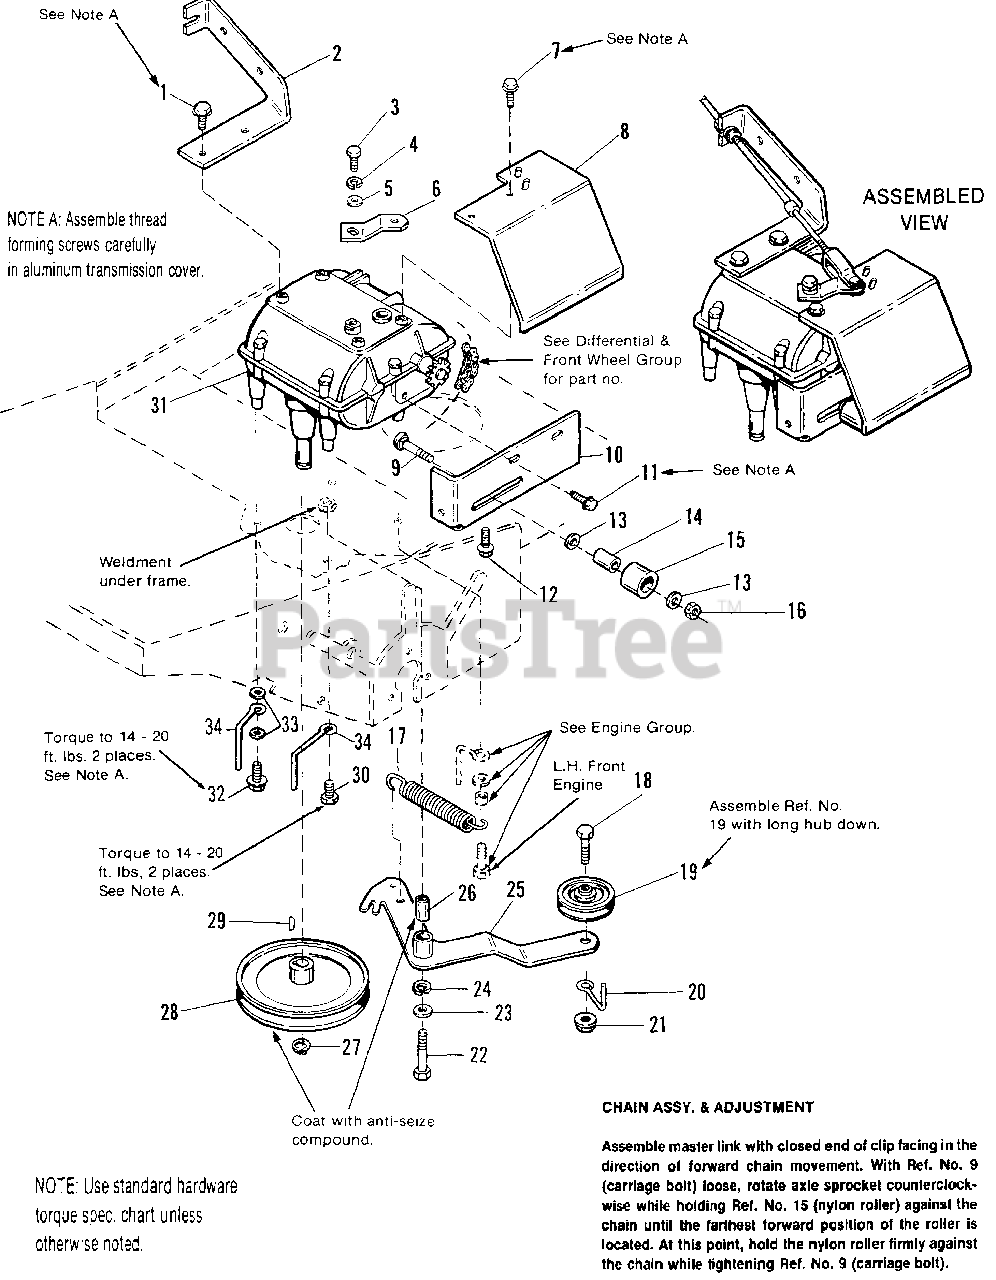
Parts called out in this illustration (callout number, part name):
1	SCREW, Taptite, 5/16-18 x 5/8
2	BRACKET, Cable
3	CAPSCREW, Hex, 1/4-28 x 5/8
4	LOCKWASHER, 1/4
5	WASHER, 5/16
6	LEVER, Shift
7	SCREW, Taptite, 5/16-18 x 1/2
8	GUARD, Chain
9	CARRIAGE BOLT, 3/8-16 x 2.0
10	SUPPORT, Transmission
11	SCREW, Taptite, 1/4-20 x 5/8
12	SCREW, Taptite, 5/16-18 x 1/2
13	WASHER, 3/8
15	ROLLER, Nylon
16	NUT, Hex Jam Lock, 3/8-16
18	CAPSCREW, 3/8-16 x 1-3/4
19	PULLEY, Idler
21	NUT, Flange Lock, 3/8-16
22	CAPSCREW, 3/8-16 x 2-1/4
23	WASHER, 3/8
24	LOCKWASHER, 3/8
25	CLUTCH ARM ASSY.
27	RING, Retaining
28	PULLEY ASSY., Transmission
29	KEY, Woodruff No. 9
30	SCREW, Hex Whizlock, 5/16-18 x 3/4
31	TRANSMISSION, 5 Speed
32	SCREW, Taptite, 5/16-18 x 1
33	WASHER, Plain, 5/16
